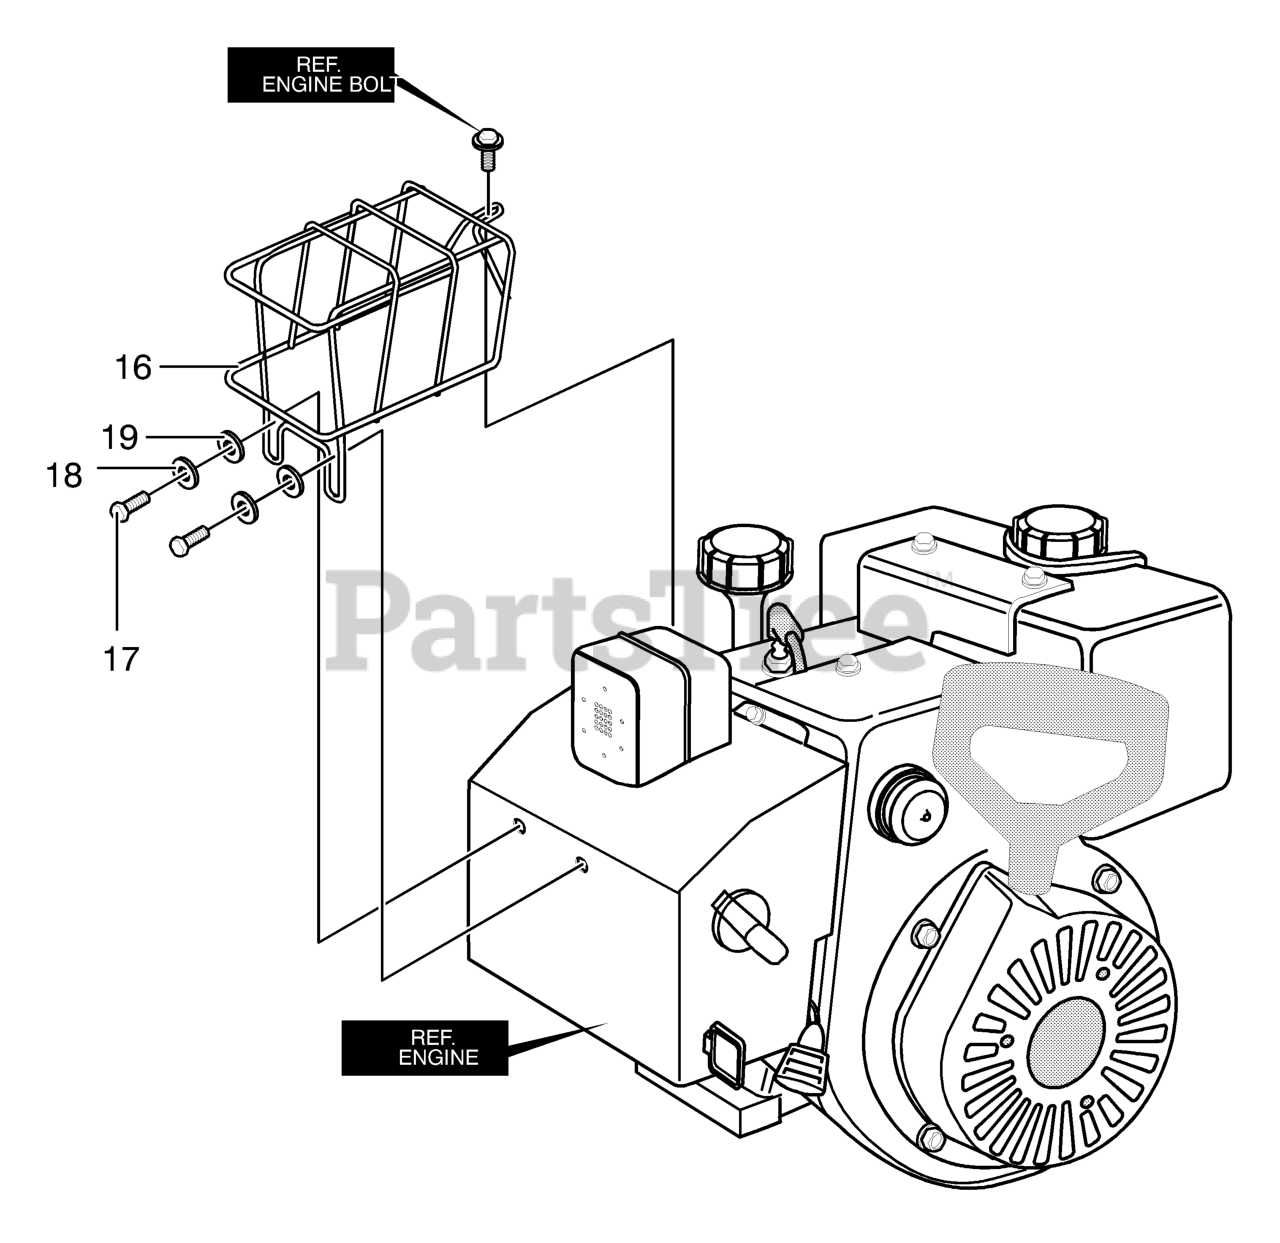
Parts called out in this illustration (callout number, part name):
16	GUARD, MUFFLER
18	WASHER
19	WASHER
